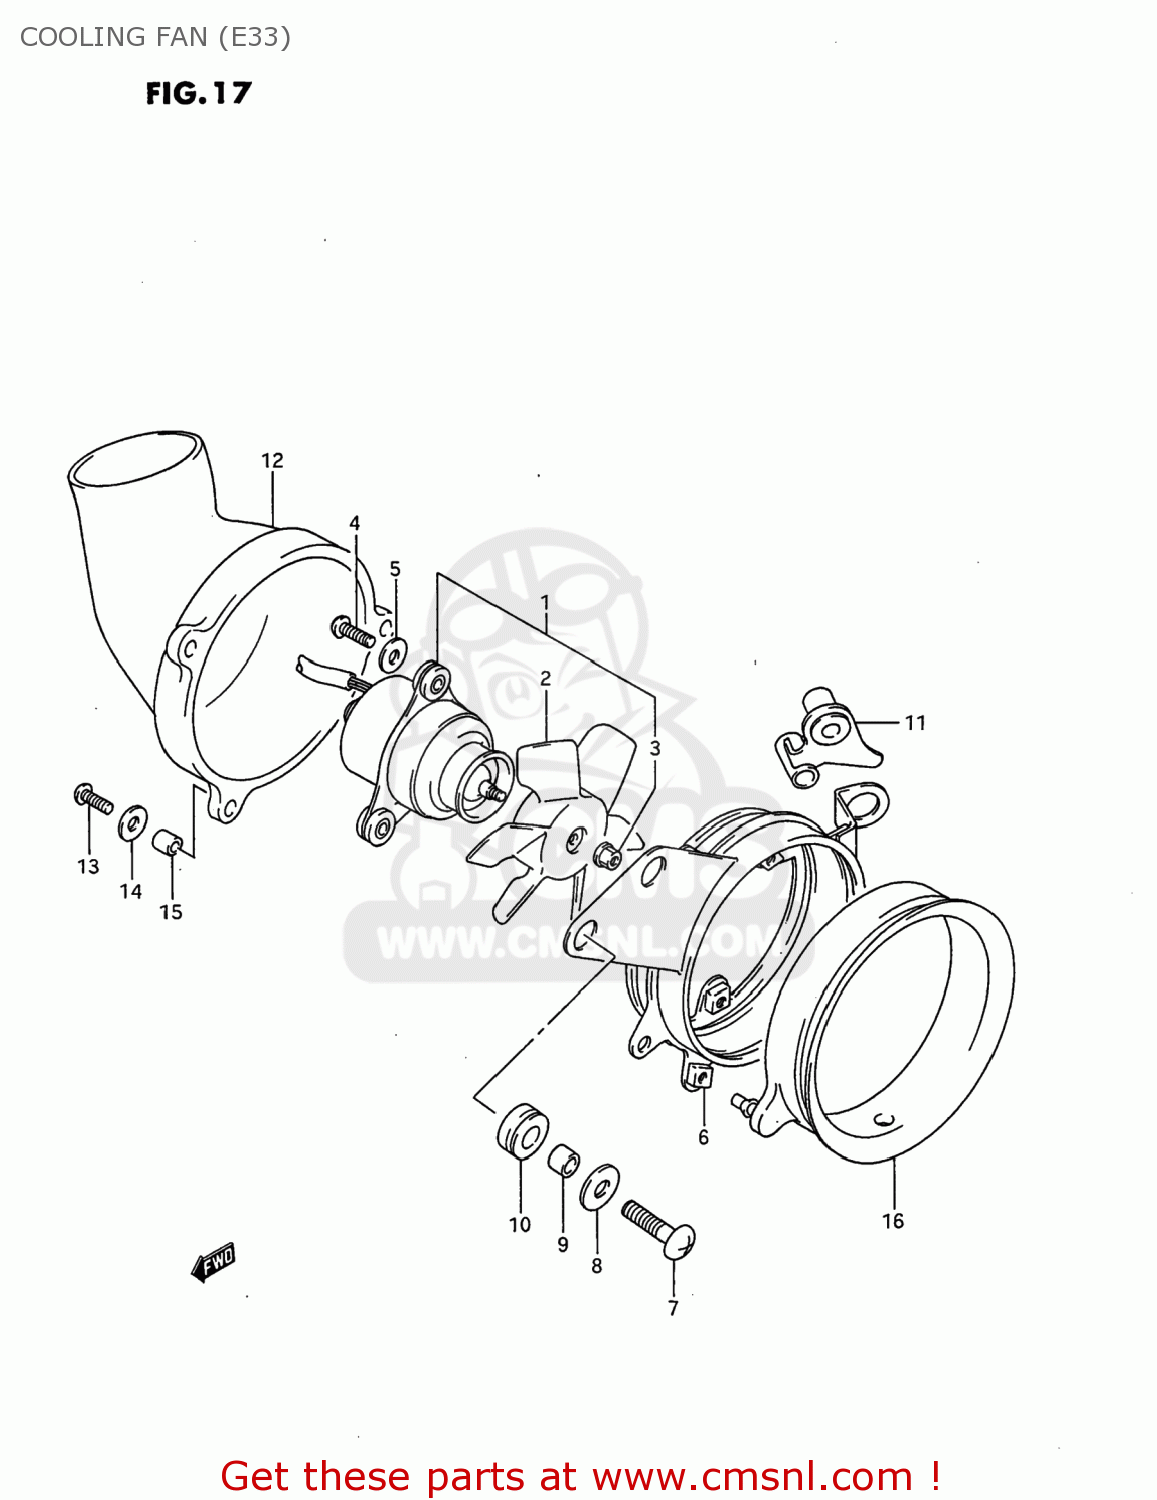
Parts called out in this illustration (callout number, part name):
1	FAN ASSY,COOLING
2	FAN
3	NUT
4	SCREW 4X16
5	WASHER (4.3X13X0.80)
6	SHROUD,FAN
7	SCREW
8	WASHER(6.5X18X1)
9	SPACER(6.5X9X6.5)
10	CUSHION
11	BRACKET,FAN SHROUD
12	DUCT,FAN COOLING NO.1
13	SCREW
14	WASHER (4.3X13X0.80)
15	SPACER(4.5X6.5X5)
16	DUCT,FAN COOLING NO.2
